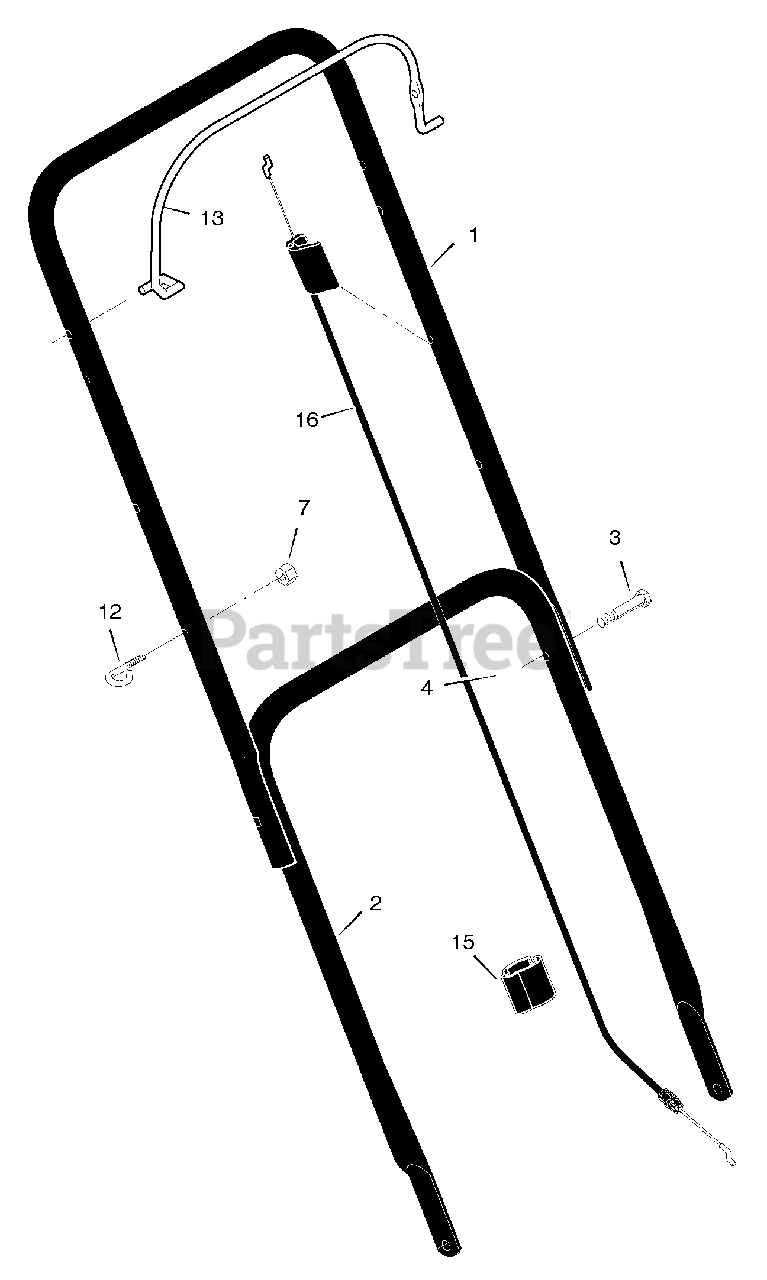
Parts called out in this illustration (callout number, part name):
1	Handle, Upper (Black)
2	Handle, Lower (Black)
4	Knob, Plastic
7	Locknut
12	Guide, Rope
13	Engine Stop Lever
15	Clamp, Cable
16	Engine Stop Cable
